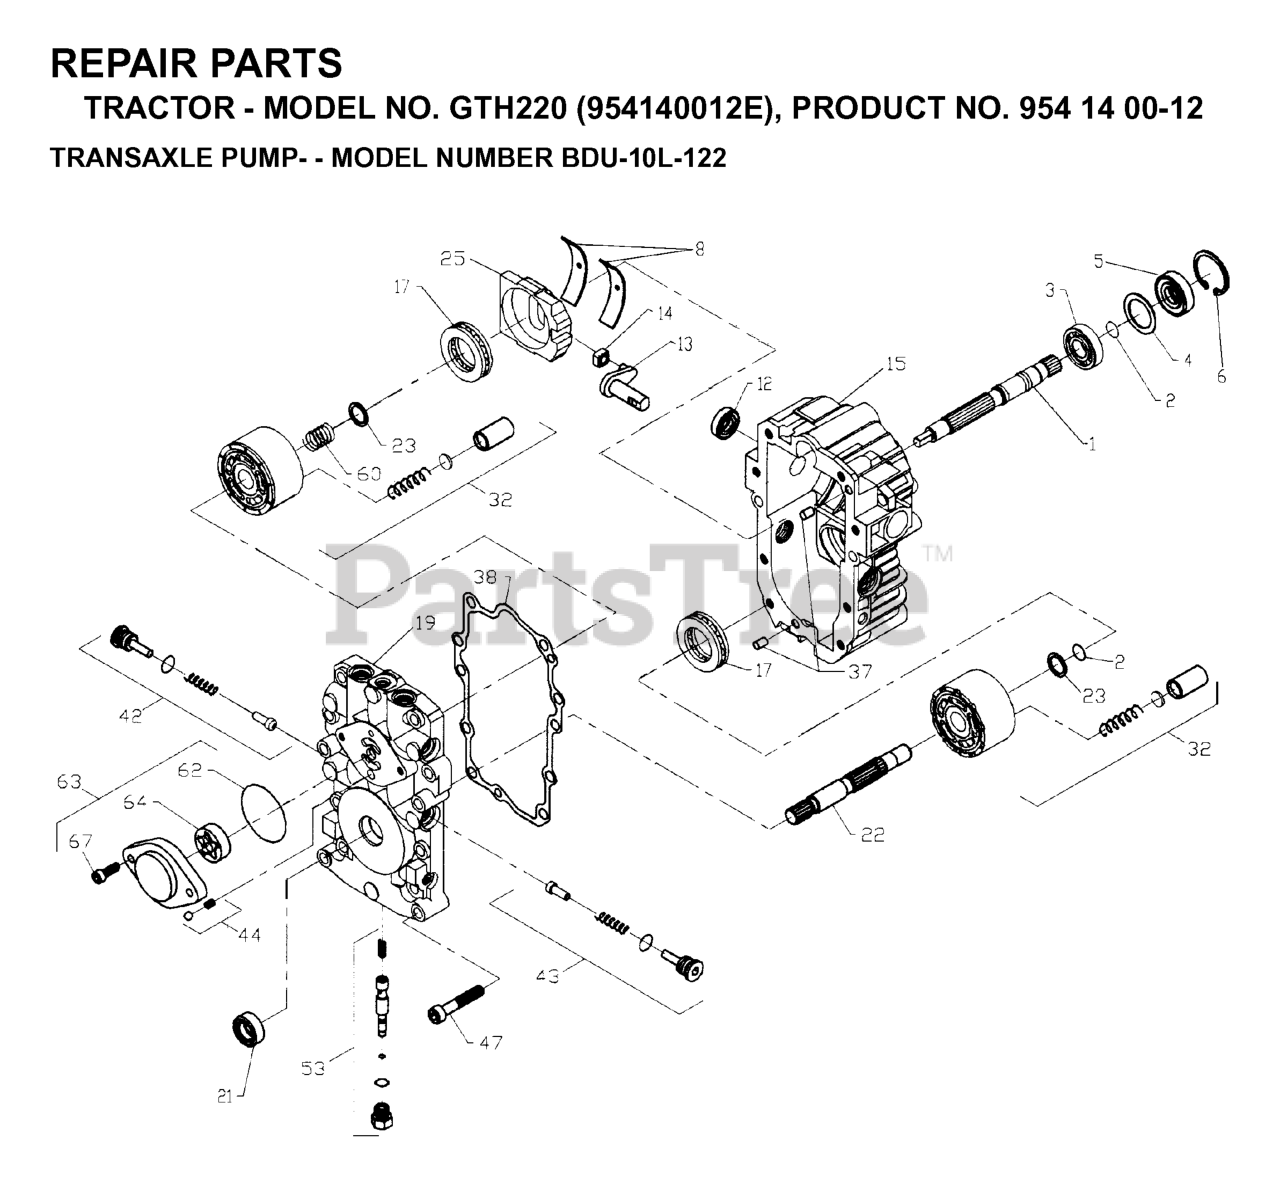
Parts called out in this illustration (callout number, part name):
3	BALL BEARING 2003043
5	SEAL LIP
6	RETAINING PIN
8	CRADLE BEARING
13	TRUNION ARM
14	GUIDE 2000015 HYD
17	BALL BEARING
21	LIP SEAL 9008000-0127
25	SWASHPLATE,VARIAB
32	BLOCK, CYL ASSY
38	GASKET 2003060
53	KIT,BYPASS VALVE(2513011)
60	SPRING 2003014
62	O-RING.HYDRO GEAR.9004101-1340
